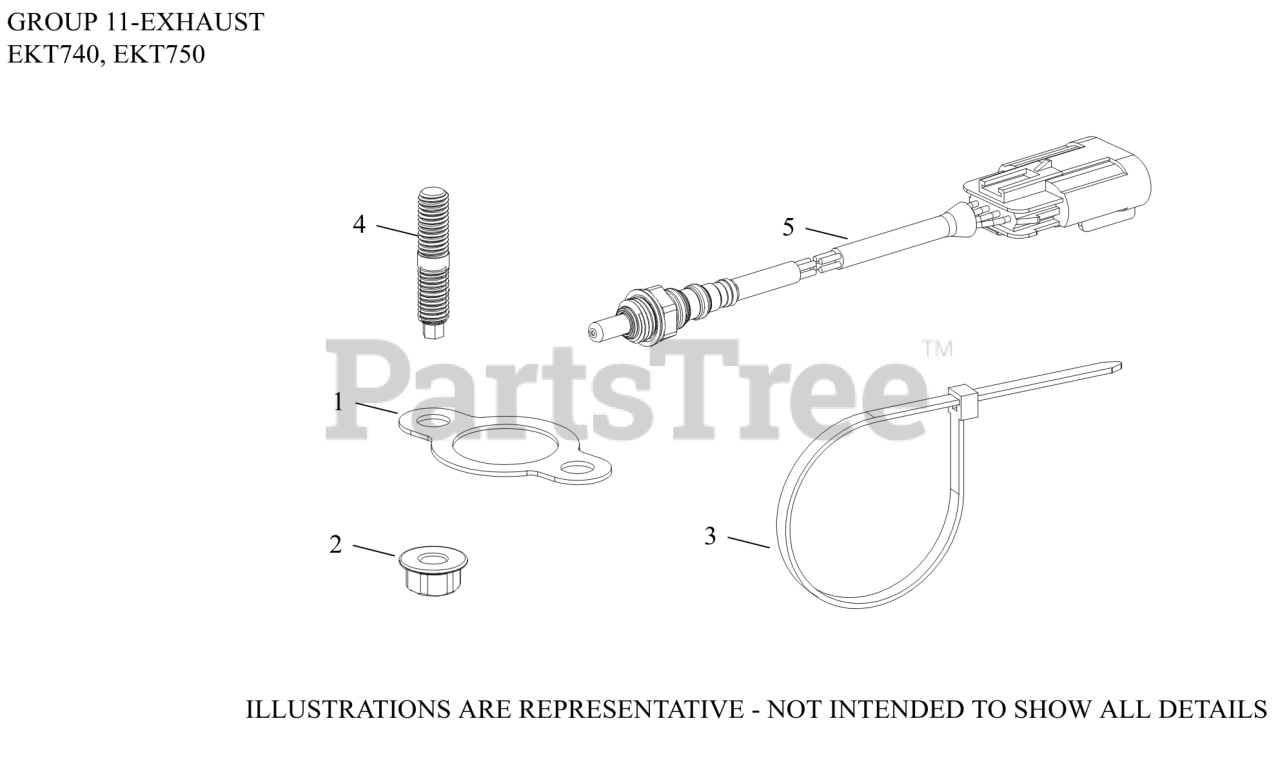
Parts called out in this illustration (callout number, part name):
1	GASKET, EXHAUST
2	NUT, HEX FLANGE LOCK (M8)
4	STUD, EXHAUST
5	SENSOR, OXYGEN-(#2541820S)
